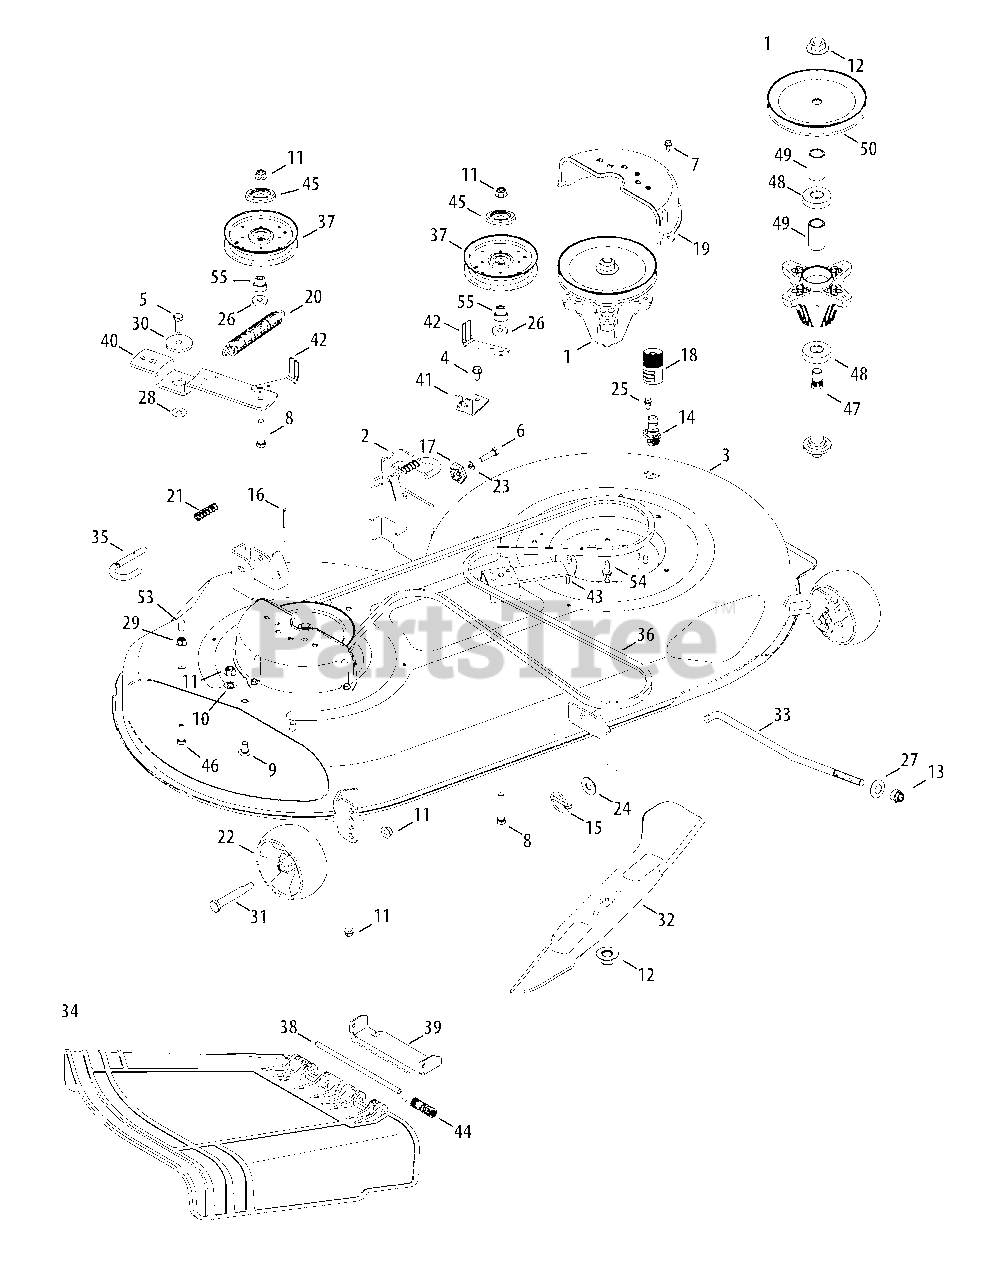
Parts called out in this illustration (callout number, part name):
1	Pulley Spindle Ass’y 6.93 dia.
2	Deck Hanger Bracket Ass’y LH
3	Deck, 46" w/2 wheel mounts
4	S-Tapp Scr 5/16-18 x .75
5	Hex Screw, 3/8-16, 1.0, Gr 5, Std
6	Hex Wash Tap Scr 5/16-18 x 1.25
7	Hex Wash S-Tapp Scr 1/4-20 x .50
8	Hex. Hd. Cap Scr. 3/8-16 x 2.0 Gr. 5
9	Carriage Bolt 3/8-16 x .75 Gr. 1
10	Push Nut, 3/8
11	Hex Flange Locknut 3/8-16 Gr. F, Nylon
12	Hex Flange Locknut 5/8-18
13	Hex Locknut 1/2-13
14	Deck Water Nozzle
15	Lynch Pin
16	Cotter Pin 1/8 x 1.25
17	Deck Gear Adjuster
18	Water Nozzle Adapter
19	Belt Cover
20	Extension Spring .94 dia. x 6.74 Lg.
21	Compression Spring .535 x 1.751
22	Deck Wheel 5.0 Dia.
23	L-Wash 5/16 ID
24	Flat Washer .531 ID x 1.25 OD x .100
25	Shoulder Screw 1/4-20 x 0.50
26	Flat Washer .385 ID x .870 OD x .092
27	Cupped Washer .63 x 1.25 x .18
28	Flat Washer .385 x 1.0 x .030
29	Hex Flange Locknut 5/16-18 Gr. F, Nylon
30	Shoulder Spacer .8540 x .200
31	Shoulder Bolt .496 x 2.5, 3/8-16
32	Blade, 23.25", 2-in-1
33	Front Lift Deck Rod
34	Side Discharge Chute Assembly
35	Deck Release Pin
36	V-Belt
37	Idler Pulley w/Flange 4.25 Dia.
38	Hinge Pin .3125 diam. x 7.96" Lg.
39	Chute Bracket
40	Idler Pivot Bracket
41	Deck Cable Engagement Bracket
42	Belt Guard Pulley Bracket
43	Deck Support Stationary Idler Brkt.
44	Torsion Spring .44 ID x 2.0
45	Pulley Cap
46	Hex Cap Screw, 5/16-18 x 1.00
47	Spindle Shaft 6.11" Lg.
48	Ball Bearing .787 ID x 1.85 OD x .551
49	Spacer .792 x 1.060 x 1.860
50	Deck Pulley 6.93 dia.
53	Cap, .290 x .50
54	Hex. TT Screw 5/16-18 x .75
55	Idler Shoulder Spacer
